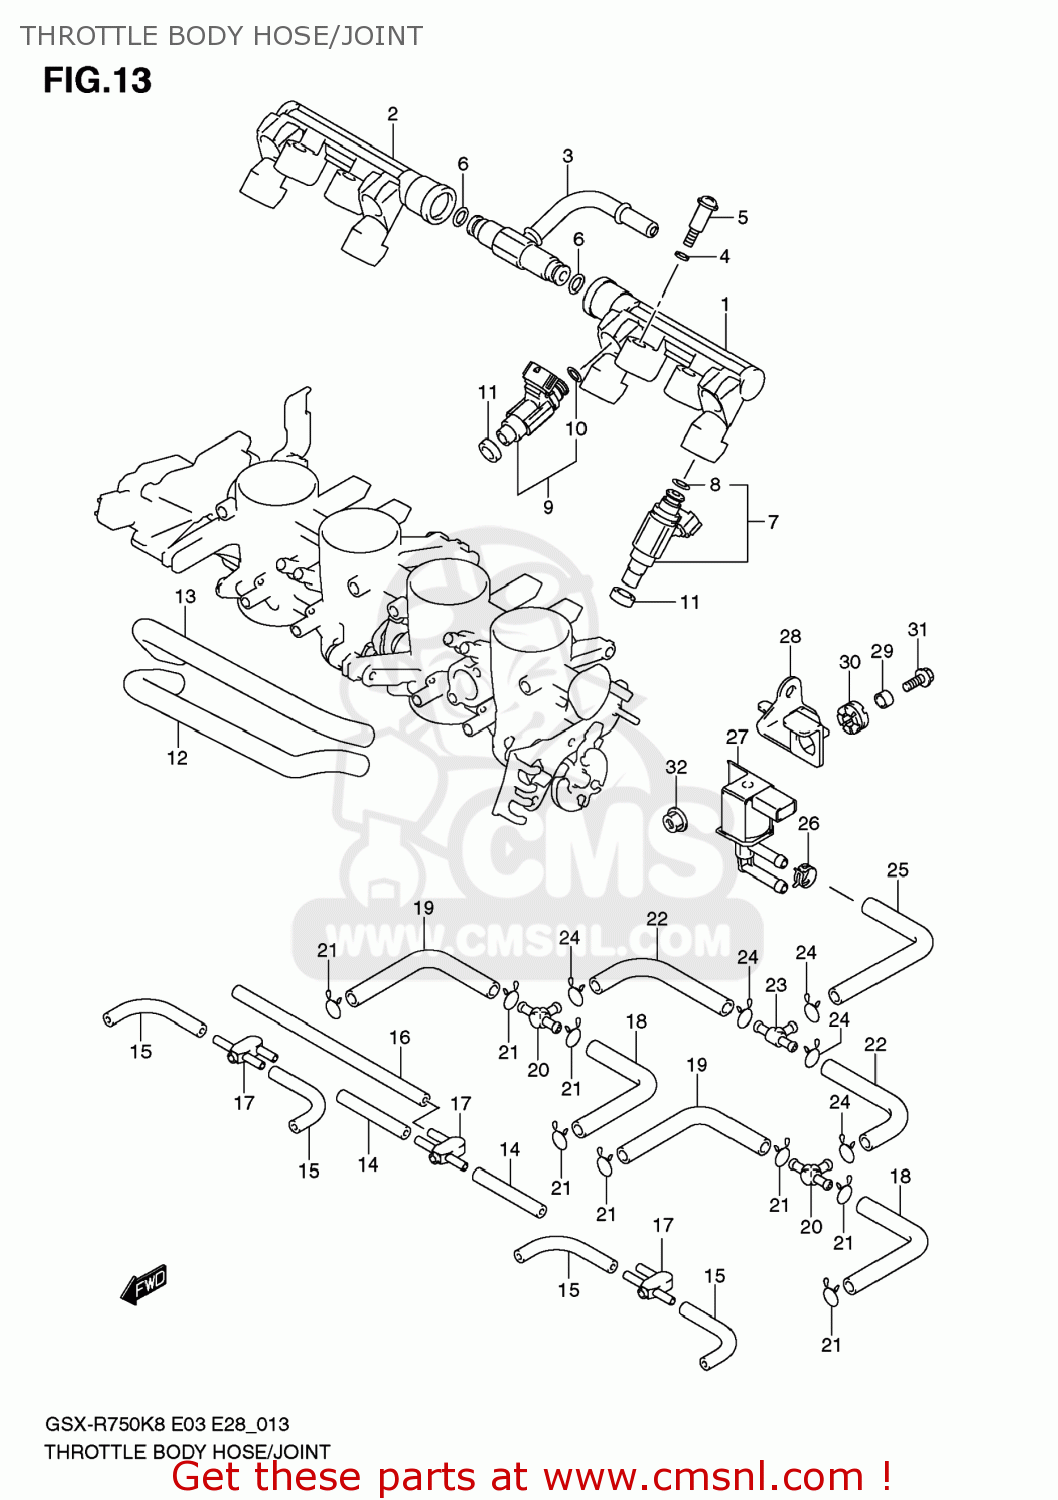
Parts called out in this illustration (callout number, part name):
1	DELIVERY PIPE ASSY
2	DELIVERY PIPE ASSY
3	NIPPLE ASSY
4	PACKING (NAS)
5	SCREW
6	O RING
7	INJECTOR ASSY
8	O RING
9	INJECTOR ASSY
10	O RING
11	SEAL
12	HOSE
13	HOSE
14	HOSE
15	HOSE
16	HOSE (3.2X7.4X200)
17	JOINT
18	HOSE
19	HOSE
20	NIPPLE
21	CLIP
22	HOSE
23	NIPPLE
24	CLIP
25	HOSE
26	CLIP
27	VALVE,CANISTER PURGE
28	BRACKET,SOLENOID VALVE
29	SPACER(6.5X10X10)
30	CUSHION
31	BOLT(6X20)
32	NUT
